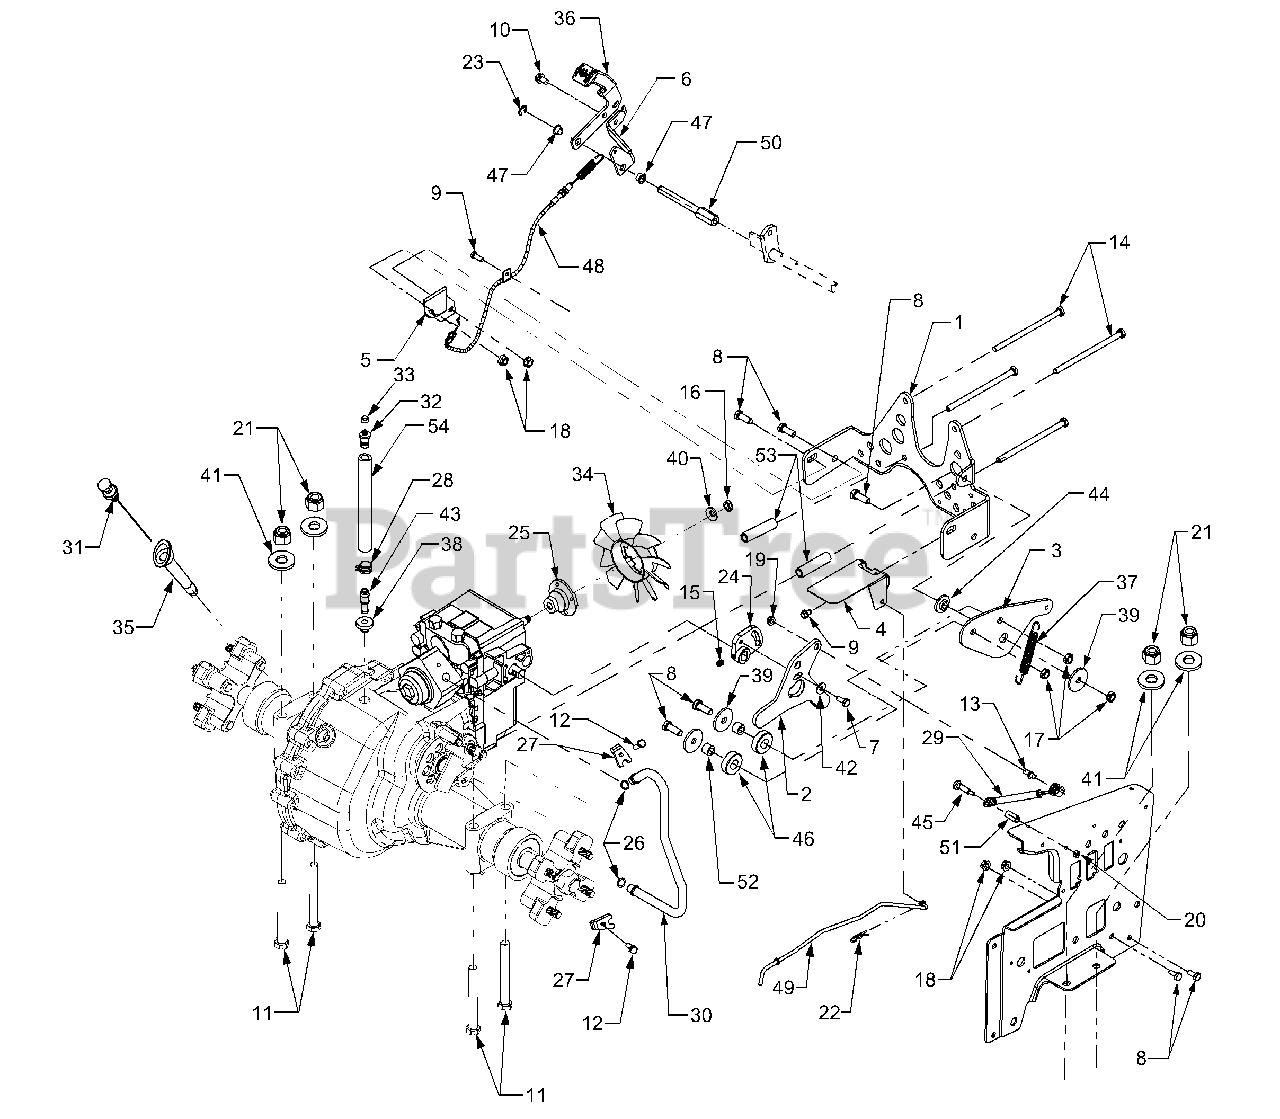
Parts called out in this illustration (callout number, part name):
1	Bracket, Torque
2	Plate, Hydro Neutral Return
3	Link, Neutral Return Bearing
5	Bracket, Cable Retainer
6	Bracket, Pedal Brace
7	Screw, Hex Cap, 1/4-20 x .625 GR5 Lock
8	Screw, Hex Cap, 3/8-16 x 1.0 GR5
9	Screw, Hex Wash. Hd. Tapp, 1/4-20 x .5
10	Screw, Hex Wash. Hd. Tapp, 3/8-16 x .75
11	Screw, Hex Cap, 1/2-20 x 4.5 GR5
12	Screw, Hex Cap, 1/4-20 x .75 GR5
13	Ball Screw, 5/16-18 x .56
14	Screw, Hex Wash. Hd. Tapp 5/16-18 x 5.5 GR5
15	Screw, Set, 5/16 x .5
16	Nut, Hex Top Lock Jam, 1/2-20
17	Nut, Hex Ctr. Lock Jam, 3/8-16
18	Nut, Hex Flange Lock, 3/8-16
19	Nut, Hex Flange Lock, 5/16-18
20	Nut, Hex, 1/4-20
21	Nut, Hex Insert Lock, 1/2-20
22	Pin, Internal Cotter
23	E-Ring, .5 Dia. Shaft
24	Arm, Hydro
25	Adapter, Pump
26	O-Ring, .426 ID x .566 OD x .070
27	Clamp, Tube
28	Clamp, Hose
29	Cylinder, Damper
30	Tube, Hydro Pickup
31	Dipstick, Transmission
32	Plastic Vent
34	Fan, Pump
35	Holder, Dipstick
36	Pedal, Diff Lock
37	Spring, Extension
39	Washer, Flat,.390 x 1.5 x
40	Washer, Bell, .5 x 1.0 x .05
41	Washer, Flat, .531 x 1.062 x .134
42	Washer, Flat, .26 x .72 x .06
43	Fitting, Tube
44	Spacer, Shoulder
45	Shoulder Bolt
46	Bearing, Ball
47	Bearing, Nylon Flange
48	Cable, Diff Lock
49	Rod, Pump Bypass
50	Shaft, Diff Lock
51	Spacer,.375 x .5 x 1.02
52	Spacer, .375 x .624 x .445
53	Spacer, Hydro, .3223 x .60 x 2.44
54	Fuel Line
